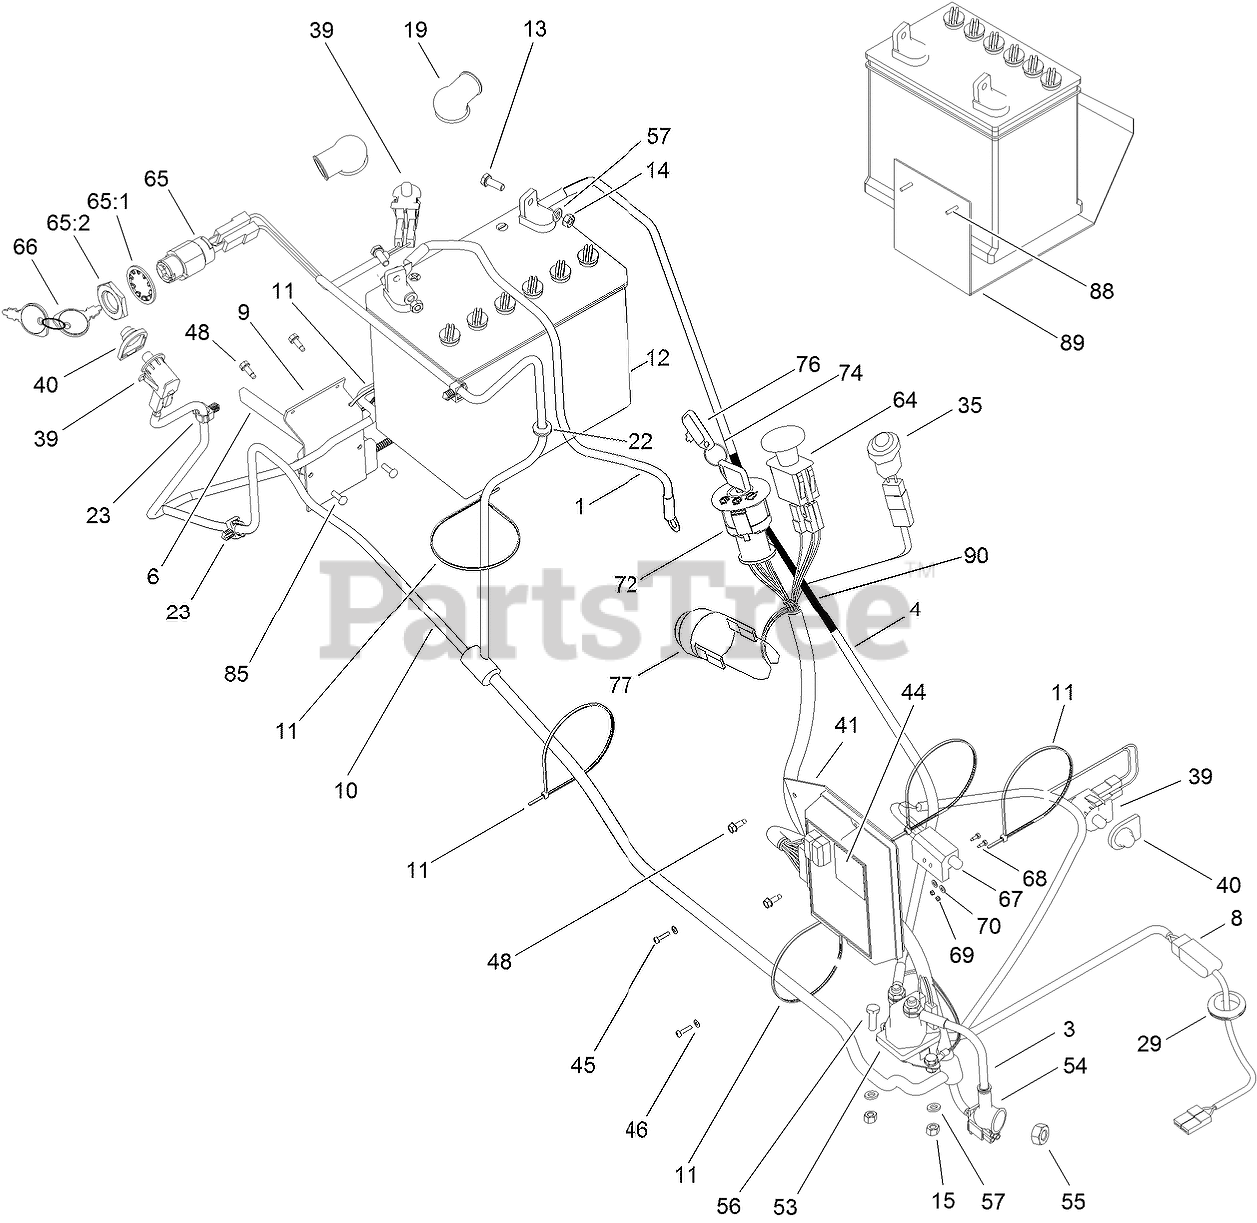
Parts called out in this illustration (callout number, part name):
1	CABLE-BATTERY, NEGATIVE
3	LEAD-STARTER, ELECTRIC
4	CABLE-BATTERY, POSITIVE
6	SWITCH-OMRON
8	HARNESS-CLUTCH
9	BRACKET-SWITCH
10	HARNESS-WIRING
11	Tie-Cable
12	BATTERY
13	SCREW-HH
14	NUT-HEX
15	NUT-LOCK
19	BOOT-RUBBER
22	BUSHING
23	CLIP-SNAP
29	BUSHING
35	LAMP-INDICATOR
39	SWITCH-DELTA
40	COVER-PROTECTIVE
41	BRACKET-SUPPORT, MODULE
44	MODULE-CONTROL
46	WASHER
48	SCREW-TAP
53	Solenoid
54	BOOT-RUBBER
55	NUT-HHF
56	SCREW-HH
57	WASHER
64	SWITCH-PTO
65	STARTER SWITCH ASM
65:1	WASHER-TOOTH, INTERNAL
65:2	NUT-HH
66	KEY-IGNITION
67	SWITCH-DELTA
69	NUT-HEX
70	WASHER
72	SWITCH-IGNITION
76	KEY-IGNITION
77	BUZZER
85	Screw
89	HOLDER-BATTERY
90	Protection-Cable
